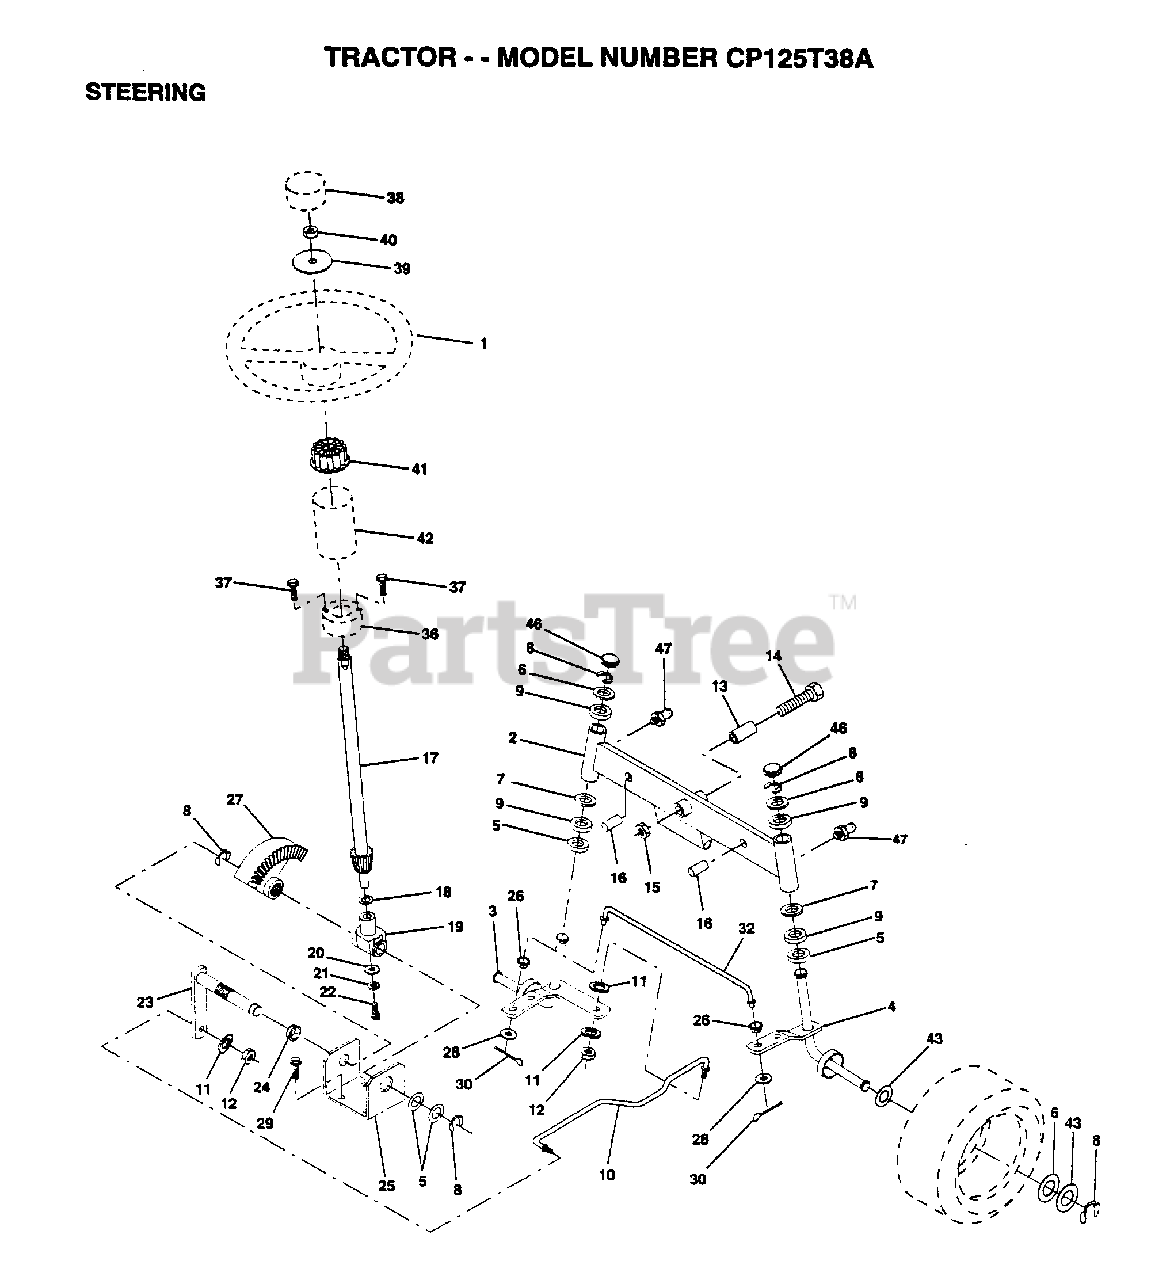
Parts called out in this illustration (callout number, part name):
2	AXLE ASM FRONT
3	SPINDLE LH
4	SPINDLE RH
5	WASHER .T
6	WASHER
7	WASHER
8	RING
9	COL. SRTG. BEAR.
11	LOCKWASHER
13	BEARING
14	BOLT HEX 5/8-11
15	"NUT-LOC,FLANGE LT"
16	AXLE PIN
17	SHAFT ASM
18	THRUST WASHER
19	SUPPORT.SHAFT
21	LOCKWASHER
22	"SCREW,SPECIAL"
24	NYLINER T
25	"BRKT,STEERING"
26	BUSHING.DRAGLINK
27	GEAR SECTOR
28	WASHER
29	SCREW
30	COTTER PIN
32	TIE ROD
38	ST WHL INSERT CAP
39	WASHER T
40	GRIPCO NUT
41	ADAPTER-WHEEL LT
42	"TUBE, STR SHAFT"
43	WASHER
46	CAP
47	ZERK M
